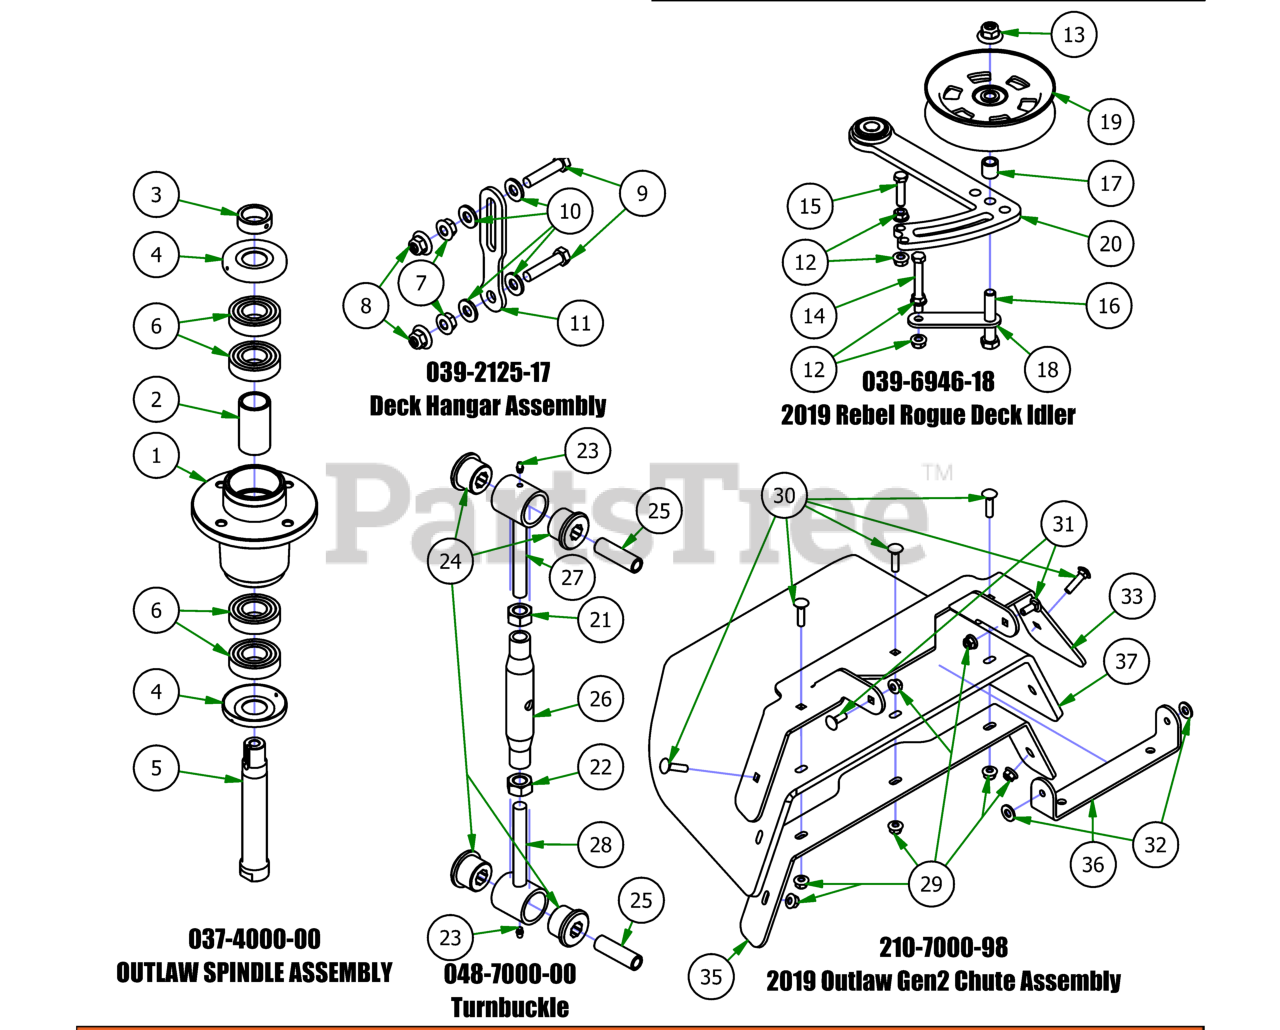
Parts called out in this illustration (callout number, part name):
1	4000 Series Spindle Housing
2	4000 Series Spindle Spacer
3	Locking Collar w/ 1/4"-20 Set Screw
4	Spindle Dust Cap
5	Spindle Shaft
6	Bearing - 6206
7	1/2" Flange Nut
8	1/2-13 NYLON INSERT FLANGE LOCKNUT ZINC
9	1/2-13X 2-1/4 GR Hex Bolts
10	.505 Nylon Spacer
11	Deck Hangar
12	3/8" Flange Nut
13	1/2-13 NYLON INSERT FLANGE LOCKNUT ZINC
14	3/8-16x3 grade 5 hex bolt
15	3/8 x 1.5" Bolt
16	1/2" x 2 3/4" Hex Bolt
17	Spacer 3/4 OD x 1/2 ID x 3\4 Length
18	Belt Tensioner Retainer Plate
19	5" Idler Pully
20	2019 Deck Tensioner
21	Hex Nut, 11/16-12
22	Hex Nut, 11/16-12 Left Handed
23	1/4" Press in Grease Fitting
24	Polyeurethane Bushing
26	2015 Outlaw Toplink Body
27	2015 Outlaw Toplink RH End
28	2015 Outlaw Toplink LH End
29	5/16" Nylon Flange Nut
30	5/16" x 1 1/4" Carriage Bolt
31	5/16" x 7/8" Carriage Bolt
32	.360 ID Plastic Washer
33	2019 Upper Chute Bracket
35	2019 Lower Chute Bracket
36	2019 Chute Hanger
37	2019 Belted Chute with Logo
